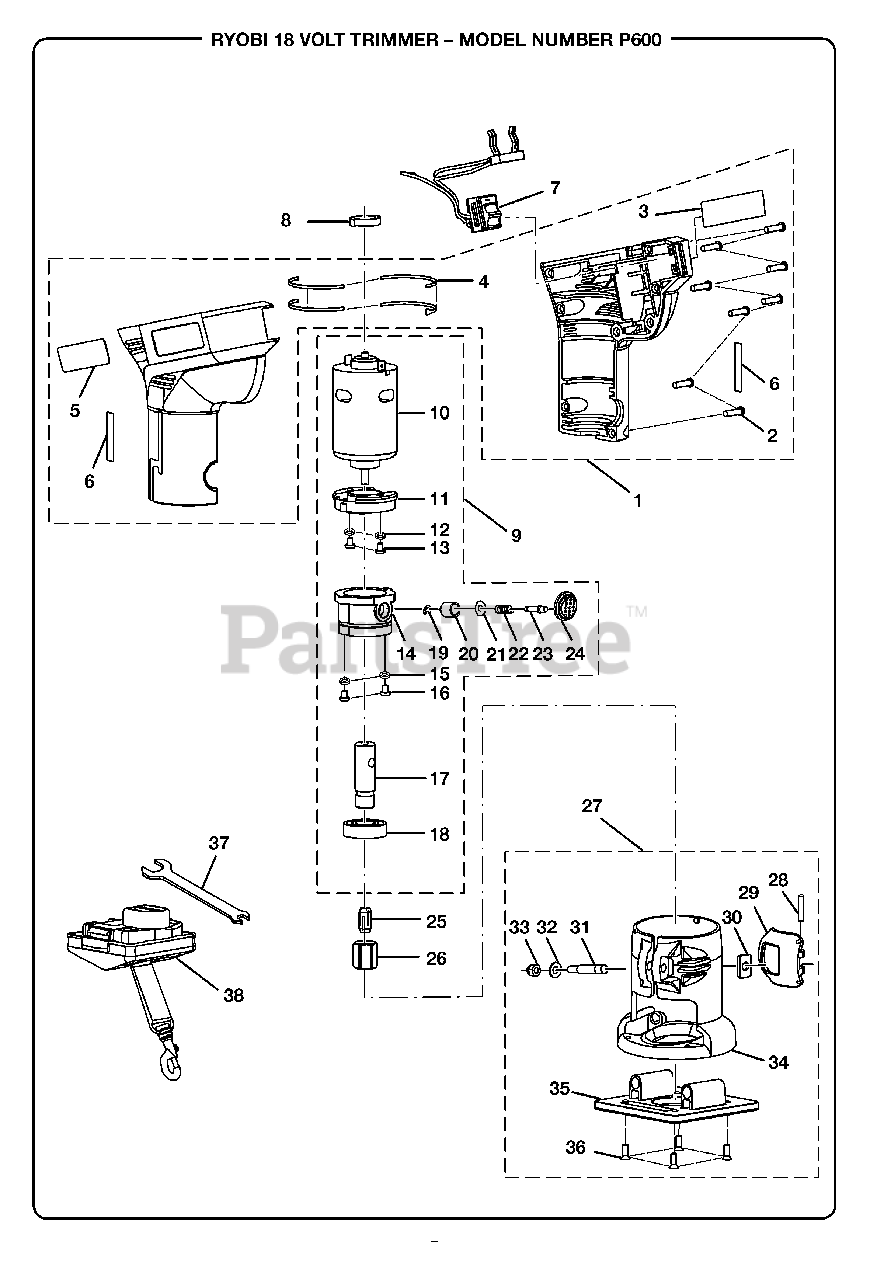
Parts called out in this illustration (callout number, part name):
1	HOUSING ASSEMBLY W / LABELS
2	SCREW (M4 X 16 mm PAN HD.)
3	DATA LABEL
4	FOAM RUBBER
5	LOGO LABEL
6	SCALE LABEL
7	SWITCH ASSEMBLY
8	MOTOR BACK RING
9	MOTOR & OUTPUT SHAFT & LOCK PIN ASSEMBLY (INC. KEY NOS.10-24)
11	MOTOR BASE
12	SPRING WASHER
13	SCREW (M5 X 12 mm PAN HD.)
14	BEARING HOLDER TOP COVER
15	SPRING WASHER
16	SCREW (M3 X 8 mm PAN HD.)
17	OUTPUT SHAFT
18	BALL BEARING
19	RETAINING RING
21	CURVED WASHER
23	SHAFT LOCK PIN
24	LOCK PIN CAP
25	COLLET (1/4 in.)
26	COLLET NUT
27	BASE ASSEMBLY (INC. KEY NOS. 28-36)
28	SPRING PIN
29	CLAMP LEVER
30	SQUARE WASHER
31	ADJUST SCREW SHAFT
33	NYLON INSERT NUT
34	BASE SUPPORT
35	SQUARE BASE
36	SCREW (M4 X 12 mm FLAT HD.)
38	PLUG IN LANYARD
